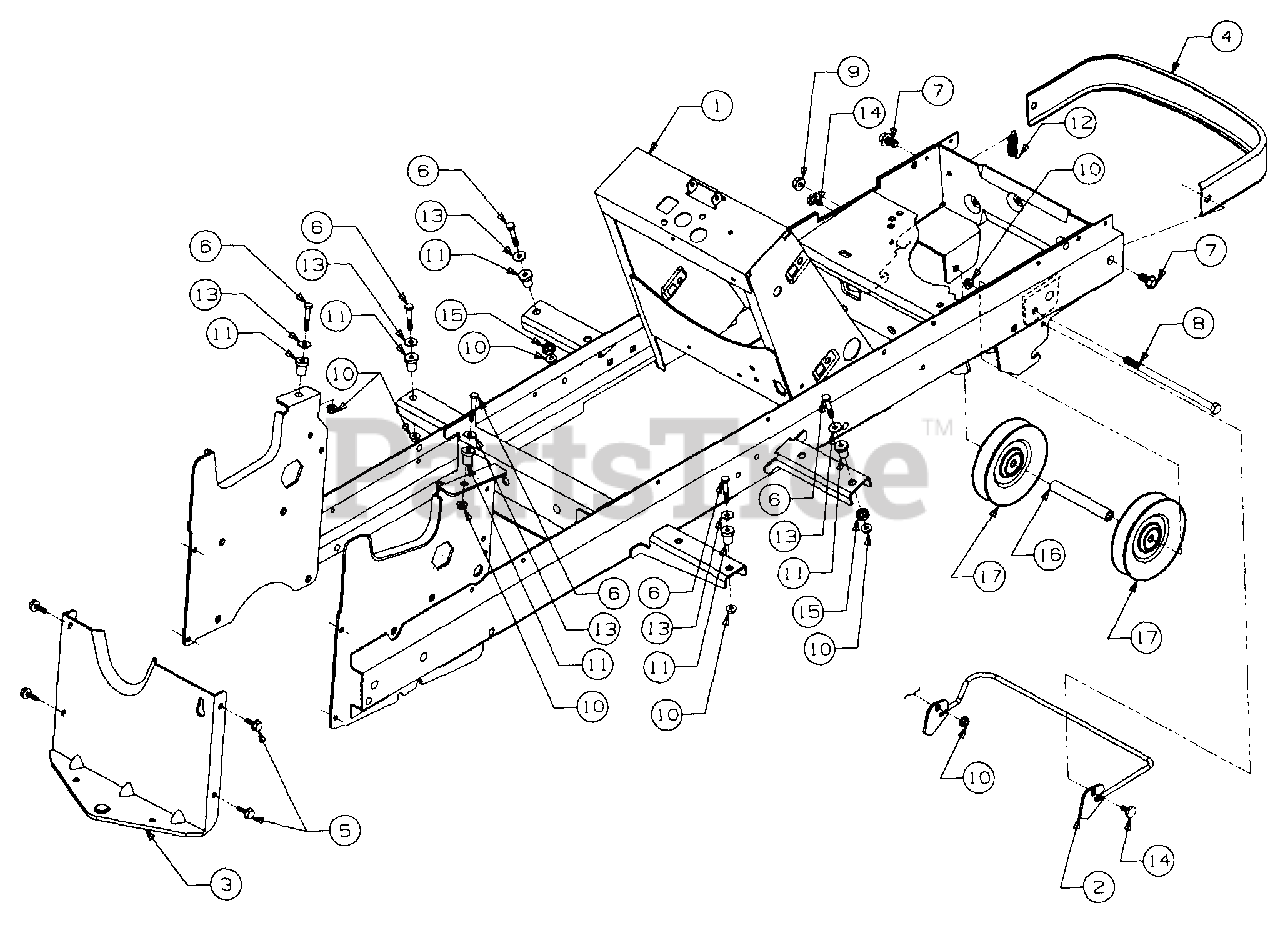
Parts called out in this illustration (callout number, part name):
6	Screw, Hex Cap, 1/4-20 x 1.5 Lg
7	Screw, Hex Wash Tapp 3/8-16 x .75 Lg
8	Screw, Hex Cap, 3/8-16 x 7.0 Lg
9	Nut, Hex Flanged Lock, 3/8-16
10	Nut, Hex Flange Lock, 1/4-20
11	Insolater, .50 OD x .88 Lg
12	Spring, Latch
13	Washer, Flat, .255 x .720 x .060 Thk
14	Bolt, Shoulder
15	Spacer, .511 ID x .70 OD x .38 Lg
16	Spacer, Idler, .407 ID x .192 OD x 4.38 Lg
17	Pulley, Idler
